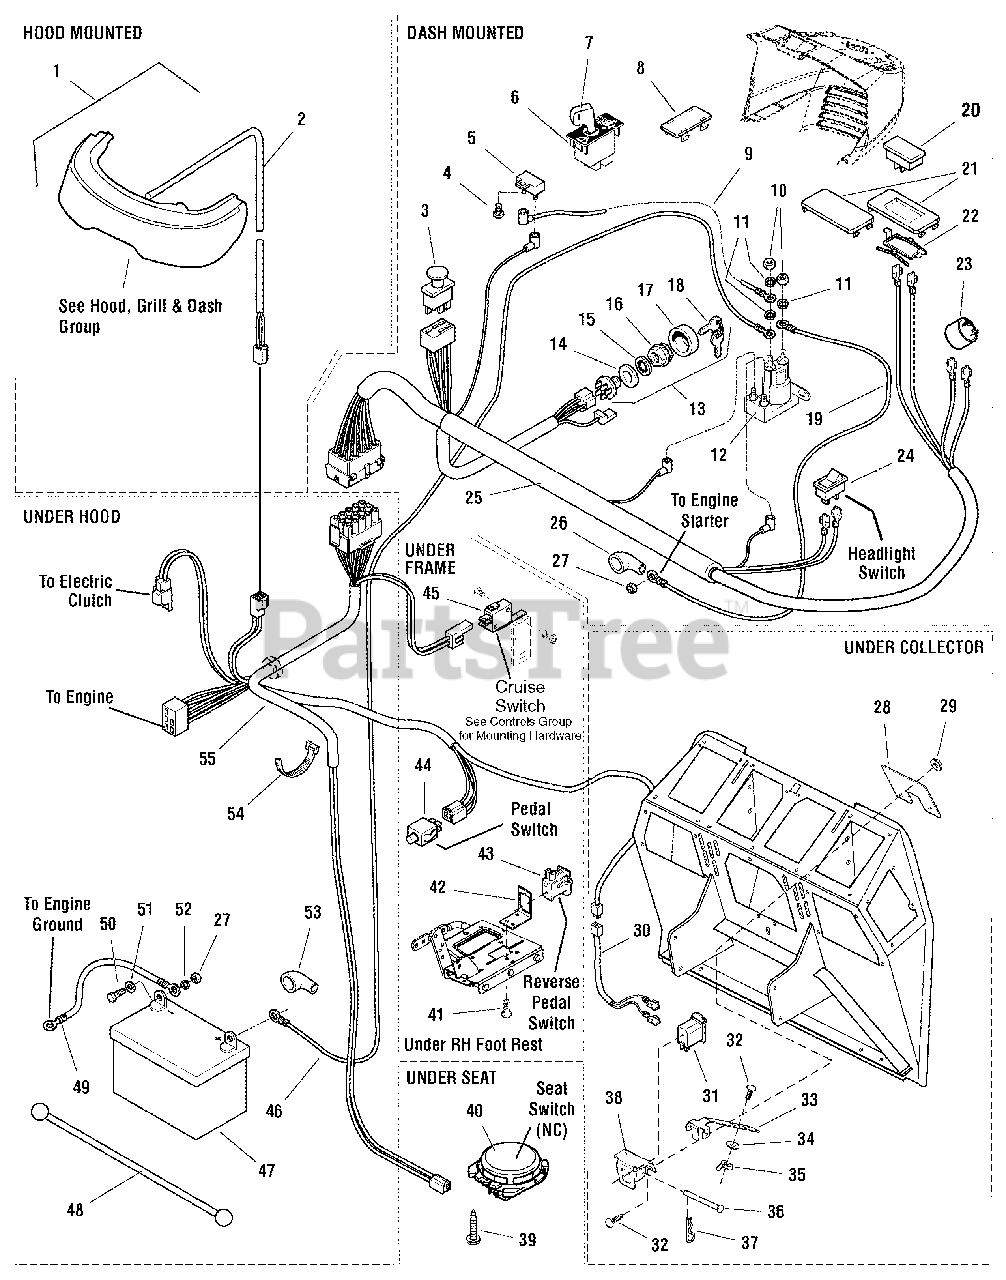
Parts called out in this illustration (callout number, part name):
1	HEADLIGHT ASSEMBLY, 4 Bulb
2	HARNESS, Headlight
3	SWITCH, PTO Push/Pull w/Symbols
4	CAPSCREW, Hex Head, 1/4 x 5/8
5	BREAKER, Circuit 12VOLT 20AMPS w/Tabs
6	SWITCH, RMO Module Only
7	KEY, RMO Module Plastic
8	PLUG, Hole Black
9	WIRE, 12GA 8 Long Red
10	NUT, Hex, 1/4-20 NC-2B
11	WASHER, Lock, External Tooth 5/16
12	SOLENOID
13	SWITCH ASSEMBLY, Ingition, 6 Pin Indak
14	WASHER, 5/8
15	LOCKWASHER, Internal Tooth, 5/8
16	NUT, Hex Flange, 5/8-32 Ignition Switch
17	COVER, Ignition Switch, Black
18	KEYS, Ignition Set of 2
19	CABLE, # 6 x 25 Long Red, 2 Ring Terminals
20	METER, Hour Digital w/Oil & Lube Alarms
21	PLUG, Dash, Hour Meter
21	PLUG, Dash, No Hour Meter Hole
22	CLIP, Hour Meter, Holds In Dash
23	BUZZER, Pulse, Grass Bag Full
24	SWITCH, Headlights, 2 Terminal
25	HARNESS, Wiring Upper
26	BOOT, Insulator, Battery Terminal
27	NUT, Hex, 5/16-24 NF-2B
28	DEFLECTOR, Switch 14GA
29	NUT, Hex KEPS Conical Washer, 1/4-20
30	HARNESS, Wiring Rear
31	SWITCH, Push Button w/Boot, Bagger
32	CARRIAGE BOLT, 1/4-20 x 5/8 G5
33	PIVOT, Actuator 14GA, E-Coat
34	WASHER, 3/8
35	NUT, Wing Lock, 1/4-20
36	PIN, Clevis
37	CLIP, Hair Pin
38	SUPPORT, Actuator 14GA, E-Coat
39	SCREW, Hex Washer Head Plastite, 1/4 x 1/2
40	SWITCH, Operator Presents, Seat NC
41	SCREW, Hex Washer Head Taptite, 1/4-20 x 3/8
42	BRACKET, Switch Mounting, RMO
43	SWITCH, Push Button, Reverse Pedal
44	SWITCH, Push Button, Foot Pedal NO/NC
45	SWITCH, Push Button, Cruise Control NO/NC Gray
46	CABLE, # 6 x 9 Long, 2 Ring Terminals
47	BATTERY, 12VOLT 6CELL 230AMPS CCA
48	STRAP, Battery 14 Long, Black Rubber
49	CABLE, # 6 x 26 Long Black, 2 Ring Terminals
50	CAPSCREW, Hex Head, 1/4-20 x 3/4 G5
51	WASHER, 1/4
52	LOCKWASHER, Spring 1/4
53	BOOT, Insulator Red, Cable Terminal
54	TIE, Self Locking, 7-5/16
55	HARNESS, Wiring Lower
